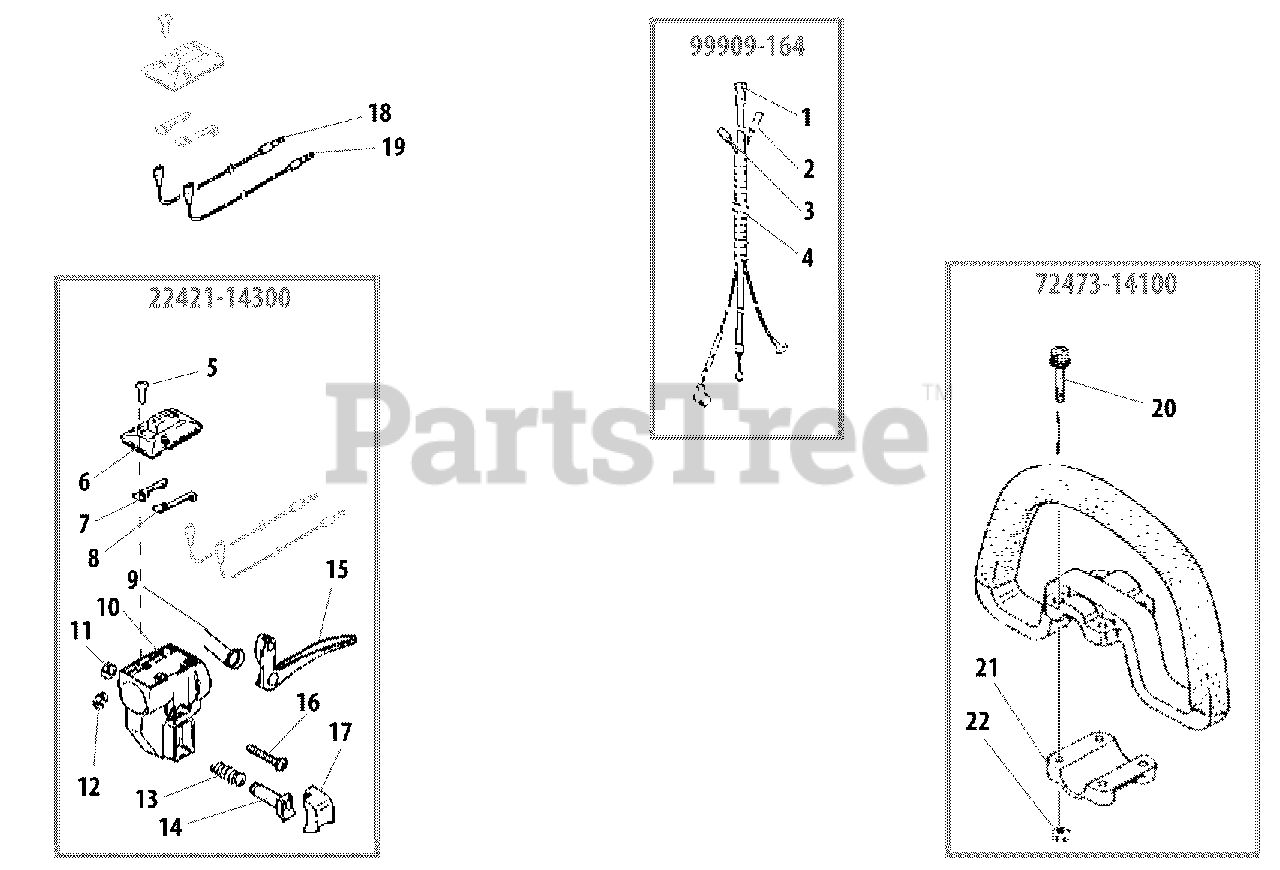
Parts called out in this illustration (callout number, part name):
1	CABLE, THROTTLE
2	LEAD - GROUND
3	LEAD - IGNITION
4	TUBE
5	SCREW -- TAPPING
6	SWITCH, IGNITION
7	TERMINAL - GROUND
8	TERMINAL - GROUND
9	SPRING, TRIGGER
10	BODY, THROTTLE
11	NUT - NYLON
12	RING, RETAINING
13	SPRING
14	SHAFT
15	TRIGGER, THROTTLE
16	SCREW - 5X20
17	BUTTON, THROTTLE LEVER
18	WIRE - RIGHT
19	WIRE - LEFT
20	SCREW - 5X30
21	CAP - LOWER
A	CONTROL CABLE ASSY
A	THROTTLE CONTROL KIT
A	HANDLE ASSY
